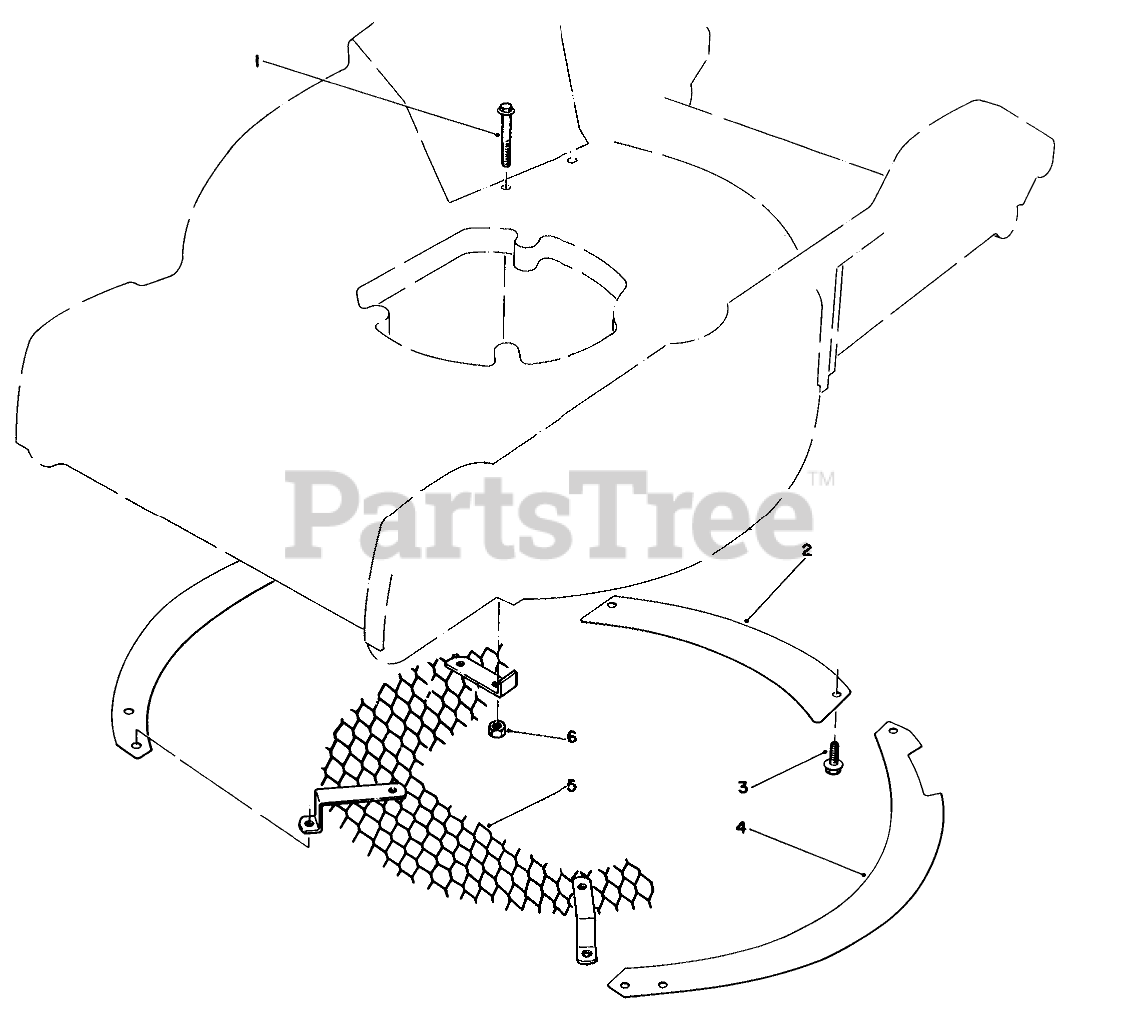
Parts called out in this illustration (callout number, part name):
1	Screw
2	Rear Baffle
3	SCREW
4	Outer Baffle
5	Screen
6	NUT-HEX, SIDE DEFORM
